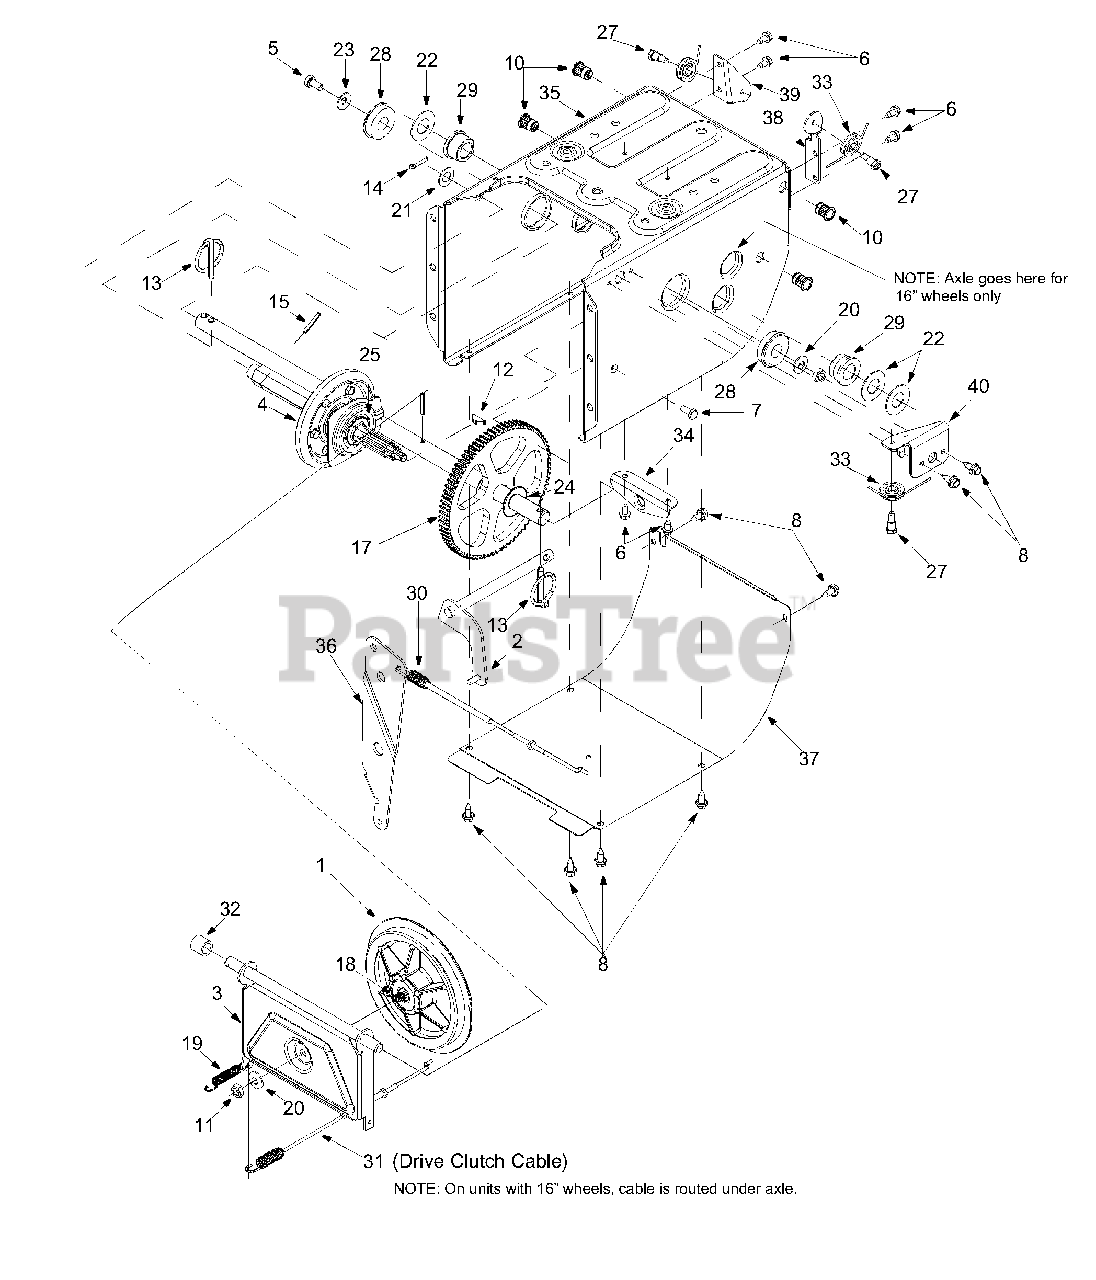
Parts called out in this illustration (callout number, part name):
1	Friction Wheel Disc Assembly
2	Shift Rod Assembly
5	Hex Bolt: 5/16-18 x .625"
6	Self-Tapping Screw 1/4-20 x 0.5"
7	Self-Tapping Screw 1/4-20 x 1.25"
8	Self-Tapping Screw 1/4-20 x .625"
10	Nut Insert 5/16-18
11	Jam Nut
13	Klik Pin
14	Cotter Pin
15	Roll Pin
17	Gear - 80 Tooth
18	Loctite (TM) Adhesive
19	Extension Spring
20	Spring Washer
21	Flat Washer
22	Flat Washer
23	Beleville Washer
24	Flat Washer
25	Lubricant
27	Carriage Screw
28	Ball Bearing
29	Hex Flange Bearing
30	Auger Clutch Cable
31	Drive Clutch Cable
32	Spacer
33	Cable Roller
